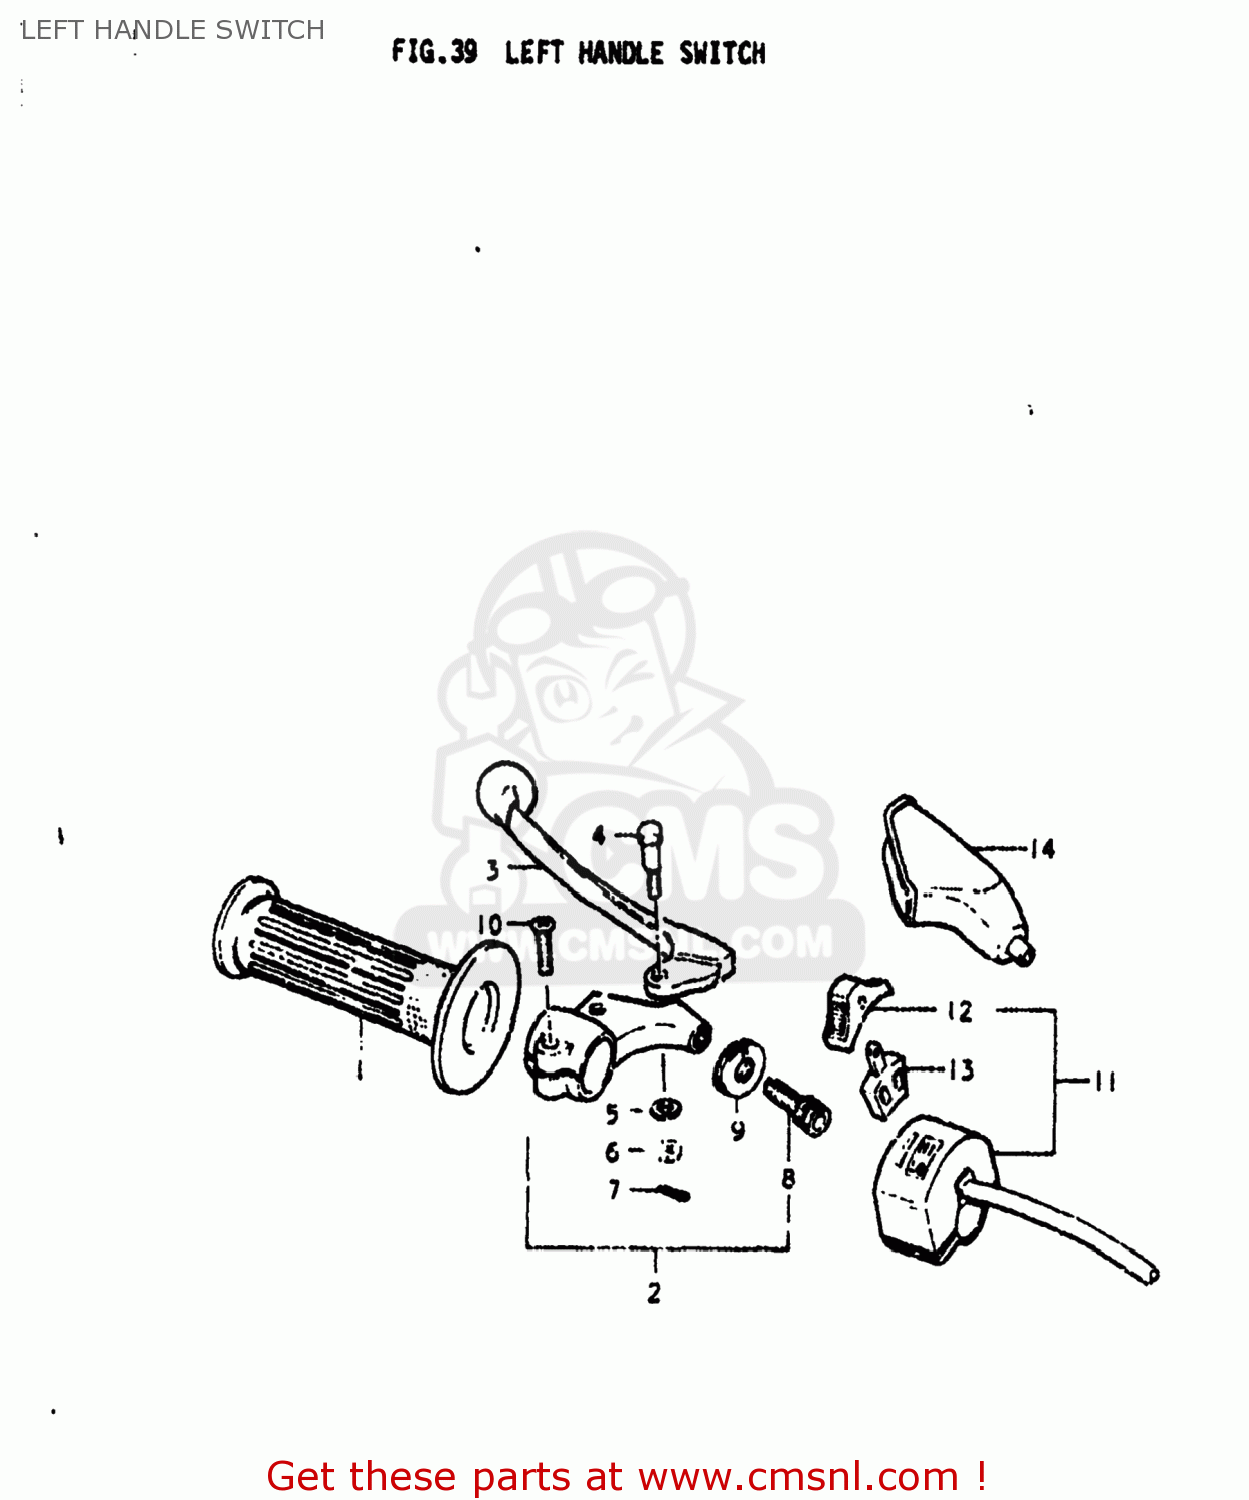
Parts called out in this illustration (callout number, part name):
1	GRIP,LEFT
2	LEVER ASSEMBLY
3	LEVER,CLUTCH
4	BOLT,LEVER
5	LOCK WASHER
6	NUT 6MM
7	COTTER PIN
8	ADJUSTER,CABLE
9	NUT,CABLE ADJUSTER
10	SCREW
11	SWITCH,DIMMER
12	KNOB,HANDLE SWITCH
13	BLOCK,LIGHTING/DIMMER
14	COVER,CLUTCH LEVER
